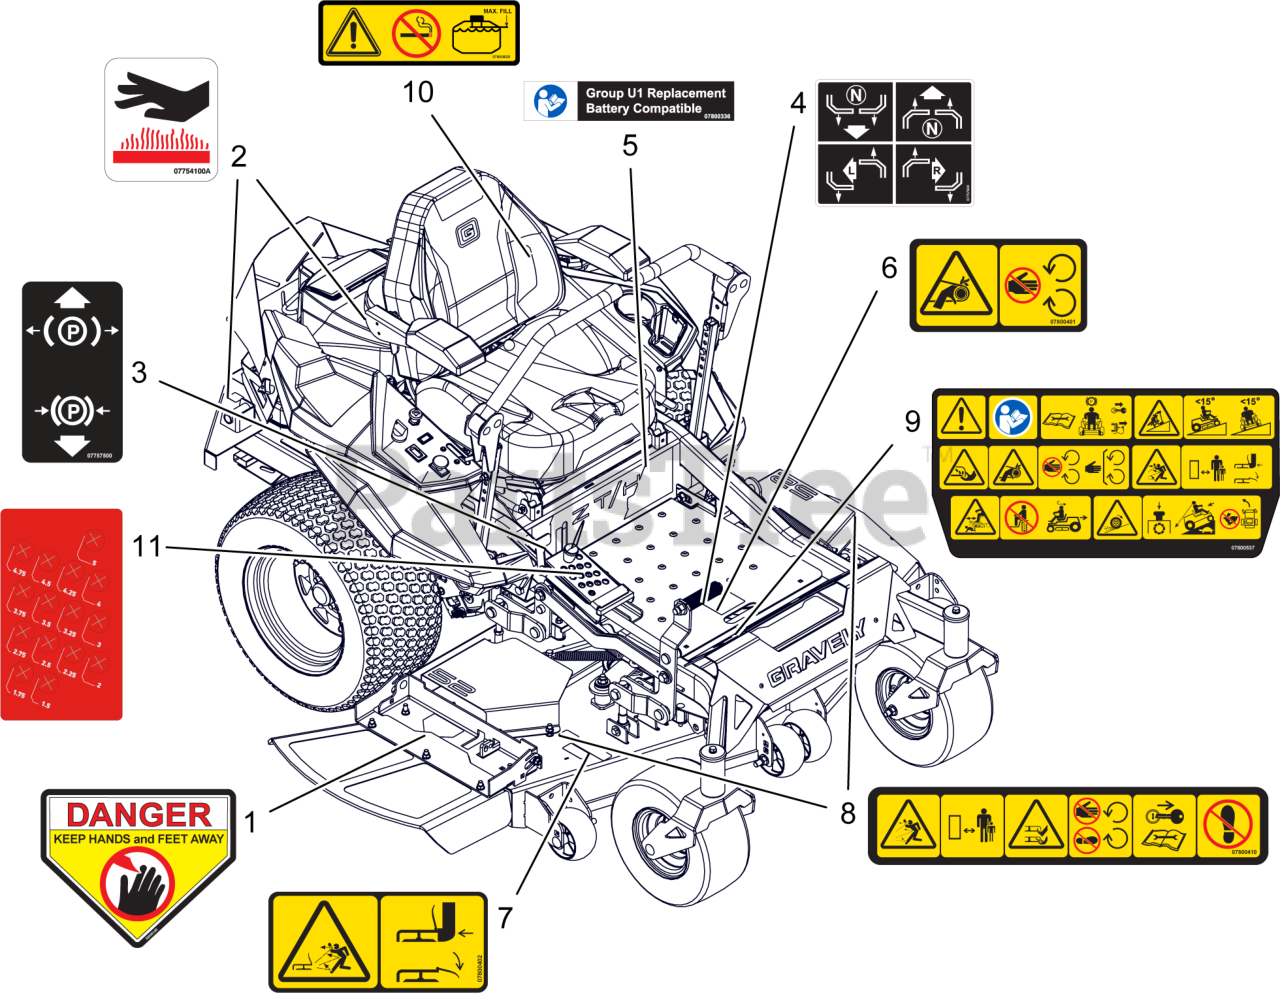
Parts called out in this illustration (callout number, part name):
1	DECAL, DANGER
2	DECAL, HOT SURFACE
3	DECAL, PARKING BRAKE LEVER
4	DECAL, INSTRUCTIONAL-STEERING
5	DECAL, U1 BATTERY REPLACEMENT
6	DECAL, SAFETY - GUARDING
7	DECAL, SAFETY - DECK GUARDING
8	DECAL, DECK SAFETY
9	DECAL, MAIN SAFETY
10	DECAL, FUEL WARNING
11	DECAL, HEIGHT OF CUT
